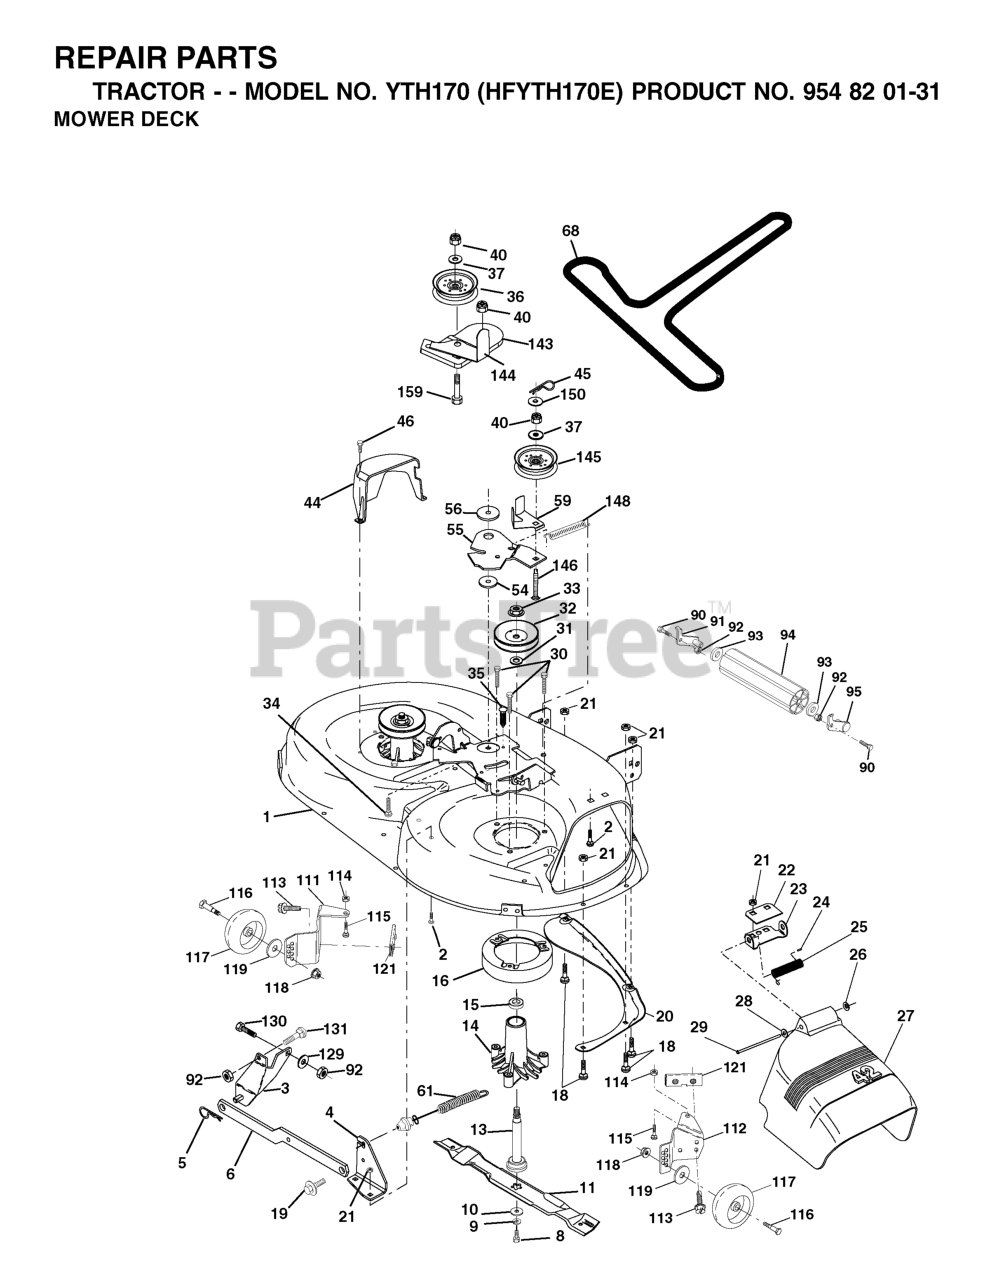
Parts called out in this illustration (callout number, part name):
1	42" DECK KIT
2	RP BOLT 5/16-18 X3/4 ZN/YEL GR
3	BRKT ASM SWAY BAR
4	BRACKET SWAY BAR 42" DECK
5	RETAINER-SPRNG RB
6	REAR SUSP ARM
8	BLADE BOLT
9	LOCKWASHER
10	WASHER.BLADE
11	Blade Mower 42" High Perf.
13	SHAFT ASM VENT
14	HOUSING.MANDREL.VENTED (MACHD)
16	STRIPPER
18	BOLT
19	BOLT SHD 5/16-18
20	BAFFLE.VORTEX
21	LOCKNUT
22	STIFFENER BRACKET
23	DEFLECTOR BRACKET
24	CAP-SLEEVE LT
25	SPRING TORSION
26	NUT PUSH M
27	SHIELD DEFLECTOR
28	Washer 11/32 x 5/8 x 16 Ga SD
29	ROD.HINGE
30	SCREW THDROL ROLLING WASHER HD
31	WASHER
32	PULLEY/MANDREL
33	NUT
35	FASTENER.XMAS.TREE
36	FLAT IDLER PULLEY
37	WASHER
44	GUARD MANDREL LH BLACK
45	RETAINER M
46	SCREW.1/4-20X5/8
54	HARDENED WASHER
55	ARM IDLER 42" MOWER LT/YT
56	SPACER.RETAINER.MOWER
59	GUARD, BELT
61	SPRING EXT ELEC CLUTCH
68	BELT V SECONDARY
90	BOLT
91	BRACKET LH (A)
92	NUT
93	Washer 1 17/32 X 7/8 X 16 Ga
94	NOSE ROLLER
95	BRACKET RH (B)
111	BRACKET WHEEL GAUGE LH 42" DK
112	BRACKET WHEEL GAUGE RH 42" DK
113	Screw Tapping 5/16-18 Unc
114	NUT
115	BOLT.CARR.5/16-18X1/2
116	BOLT M
117	WHEEL.GAUGE.STANDARD
118	LOCKNUT
119	WASHER.5/16.FLAT.STE.STD.
121	BRACKET.EXTRUDED.GAGE.WHEEL
129	WASHER
131	BOLT D
143	BRACKET, ARM IDLER
144	DNO KEEPER.BELT.42".CLUTCH.CBL
145	PULLEY
146	BOLT, CARRIAGE IDLER BLACK
148	IDLER RETURN SPRING
149	SPRING.RETAINER.YELLOW.ZINC
